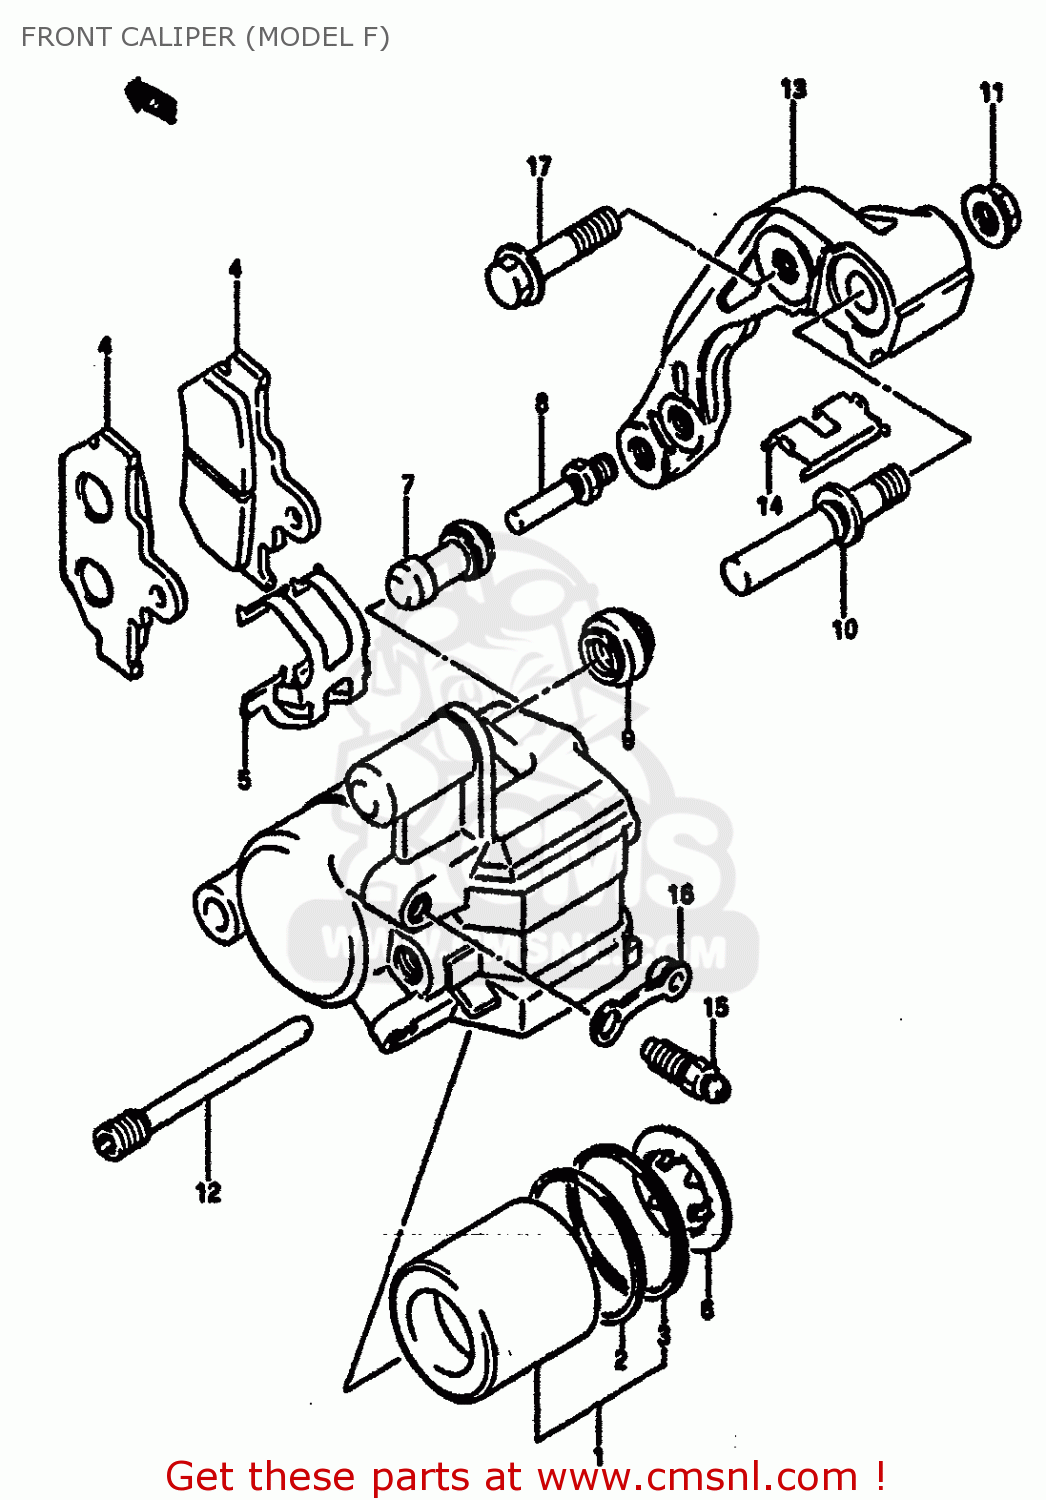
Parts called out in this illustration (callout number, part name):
1	PISTON SET,CALIPERS
2	SEAL,PISTON
3	DUST SEAL,PISTON
4	PAD
5	SPRING
6	SHIM
7	BOOT
8	PIN,BOLT
9	BOOT
10	PIN,SLIDE
11	NUT,SLIDE PIN
12	PIN,HANGER
13	BRACKET
14	RETAINER
15	BLEEDER
16	CAP,BLEEDER
17	BOLT
